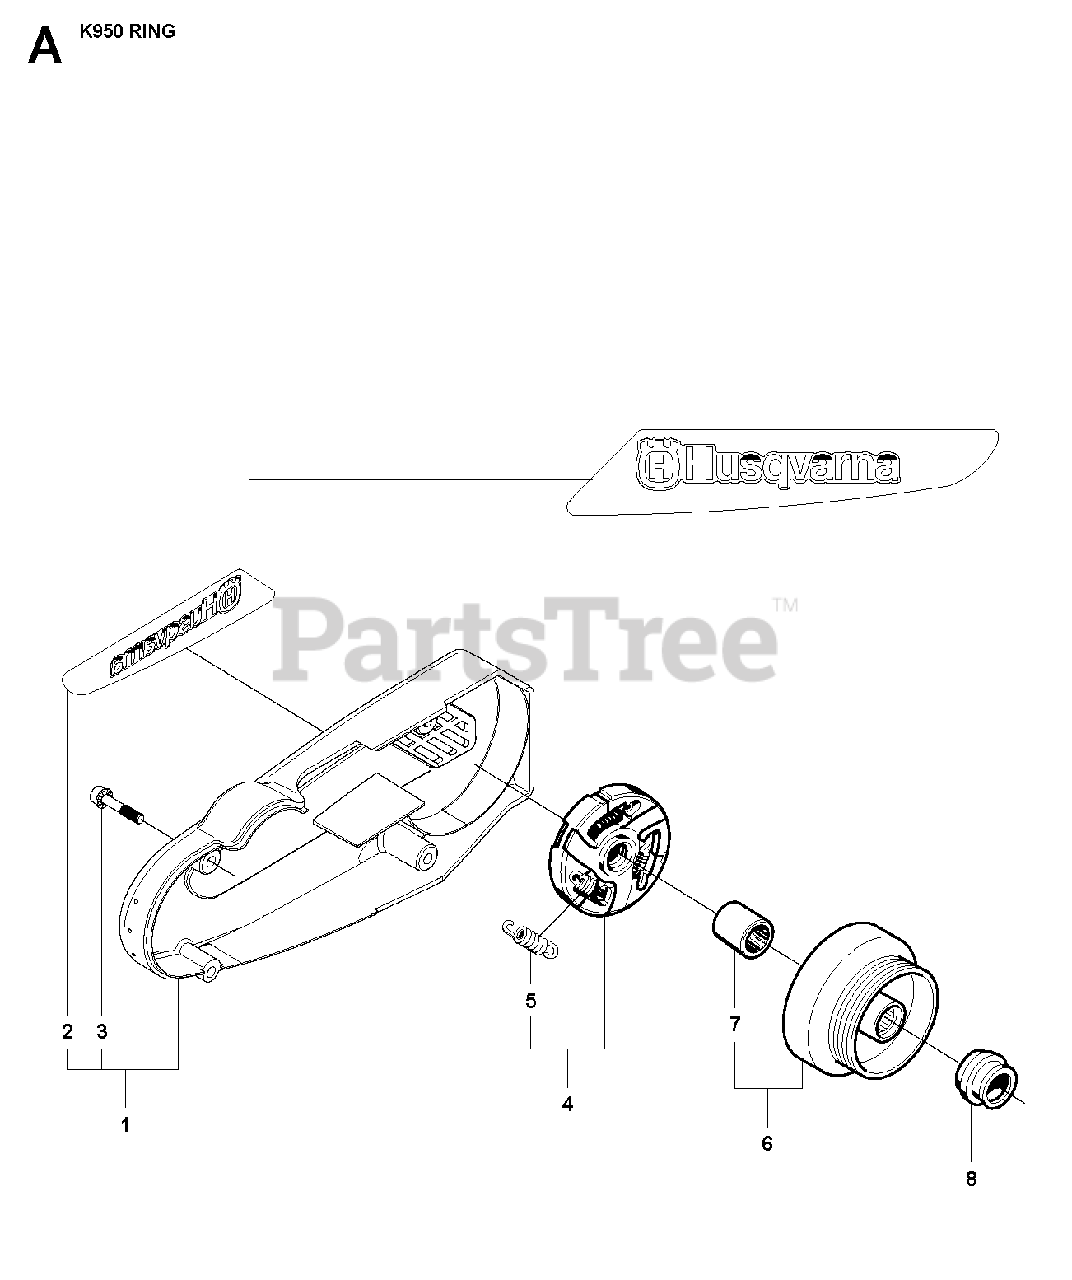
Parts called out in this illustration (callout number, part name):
3	SCREW CCRPANMO
4	CLUTCH ASSYIncl. 5
5	CLUTCH SPRING
6	DRIVING PULLEY ASSYIncl. 7
7	NEEDLE BEARING
8	SPACING SLEEVE
